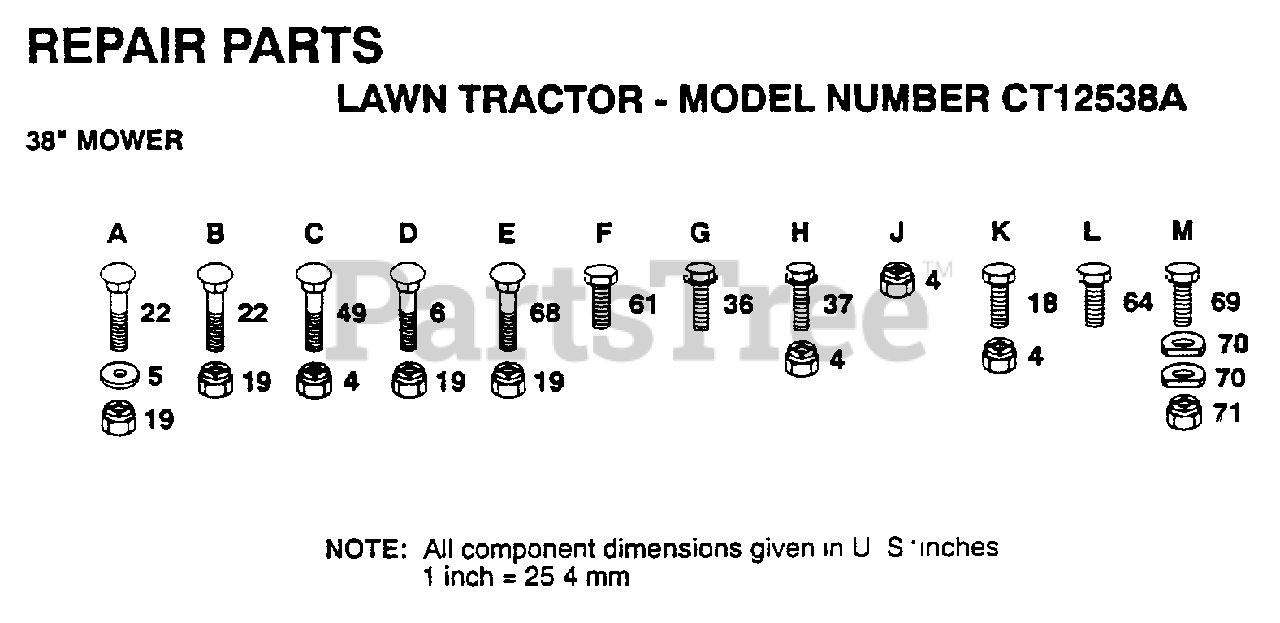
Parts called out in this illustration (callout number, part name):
5	WASHER M
6	BOLT
22	BOLT
36	SCREW
37	SCREW
49	BOLT
61	BOLT
64	BOLT.3/8-14X1.25
69	BOLT LT
70	WASHER T
